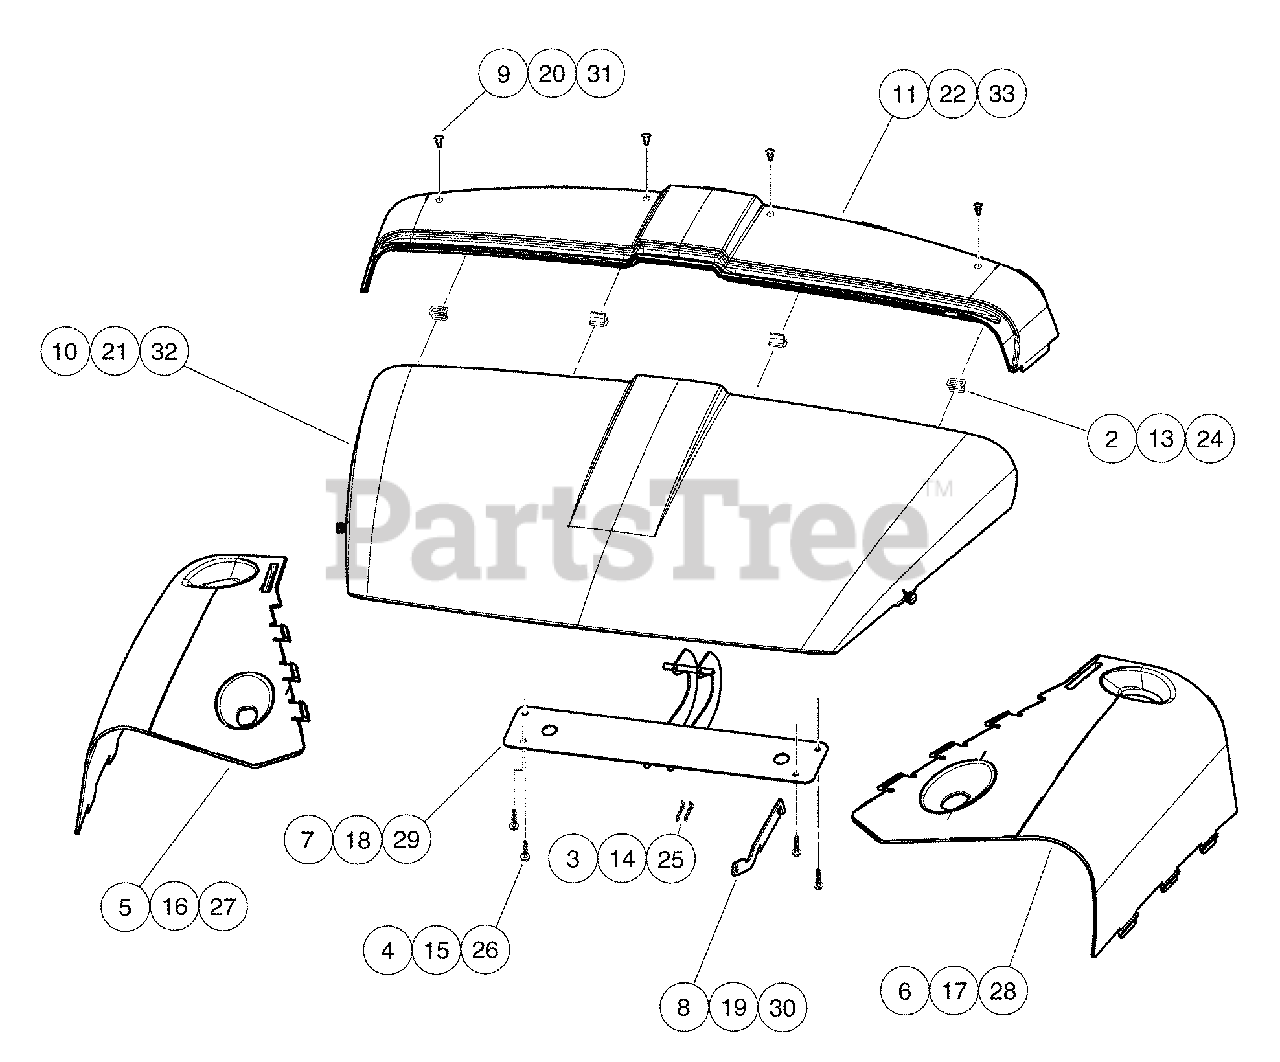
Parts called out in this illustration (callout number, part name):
1	Option, Color, Huv, Camo
2	Clip-body-trim
3	Pin, Bow Tie Locking - .072
4	Screw,m6,torx,interlock,thread
5	Panel, Cowl, Passenger-Side, Real Tree Camo
6	Panel, Cowl, Driver-Side, Real Tree Camo
7	Weldment, Hinge, Hood
8	Prop, Hood
9	Rivet, Removable, Tuflok 1/4"
10	Hood, Design B, Moff
11	Panel, Cowl, Upper, B,moff
12	Option, Color, HUV, Orange
13	Clip-body-trim
14	Pin, Bow Tie Locking - .072
15	Screw,m6,torx,interlock,thread
16	Panel, Cowl, Ps, Orange
17	Panel, Cowl, Drv, Orange
18	Weldment, Hinge, Hood
19	Prop, Hood
20	Rivet, Removable, Tuflok 1/4"
21	Hood, Design B, Orange
22	Panel, Cowl, Upper, B, Orange
23	Option, Color, Huv, Olive Grn
24	Clip-body-trim
25	Pin, Bow Tie Locking - .072
26	Screw,m6,torx,interlock,thread
27	Panel, Cowl, Ps, Olive Green
28	Panel, Cowl, Drv, Olive Green
29	Weldment, Hinge, Hood
30	Prop, Hood
31	Rivet, Removable, Tuflok 1/4"
32	Hood, Design B, Olive Grn
33	Panel, Cowl, Upper, B, Olv Grn
